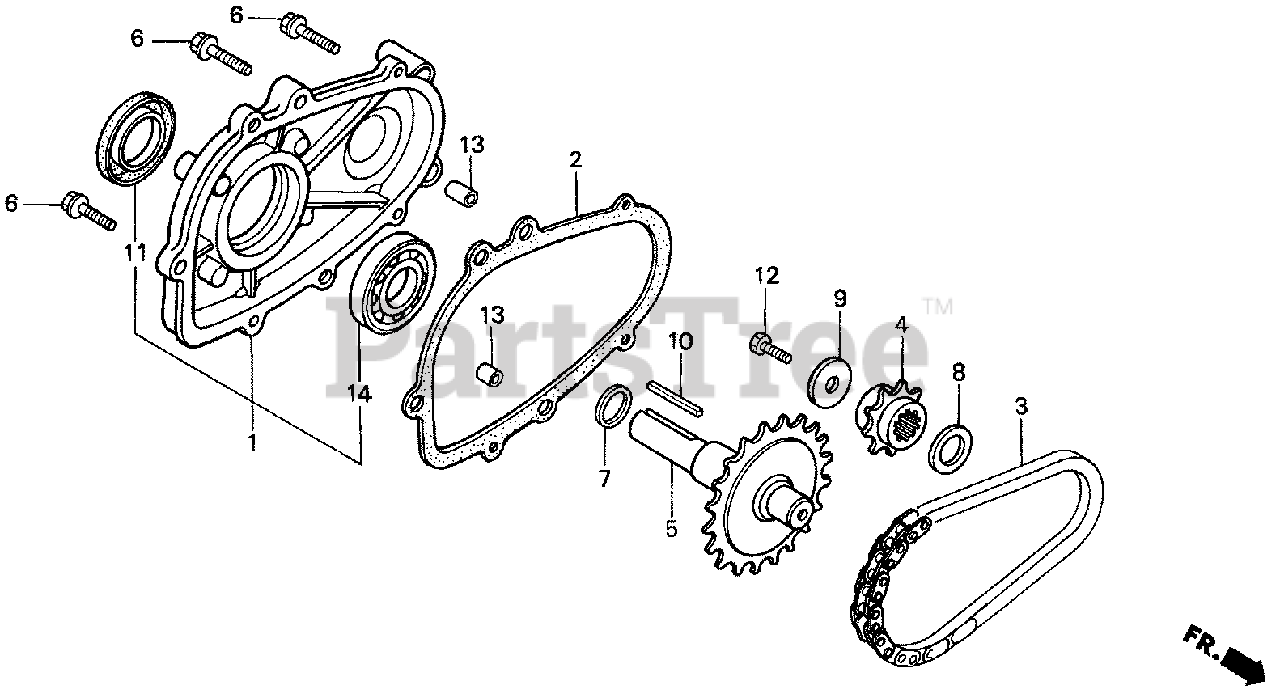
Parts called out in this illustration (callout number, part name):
1	COVER ASSY., CHAIN CASE
2	GASKET, CHAIN CASE COVER
3	CHAIN, P.T.O. DRIVE
4	SPROCKET, DRIVE
5	SHAFT, P.T.O.
6	BOLT, FLANGE (6X28)
7	SPRING, THRUST
8	SPACER (20MM)
9	WASHER (8MM)
10	KEY (5X5X33)
11	OIL SEAL (25X41X6)
12	BOLT, HEX. (8X25)
13	PIN A, DOWEL (8X14)
14	BEARING, RADIAL BALL (6205)
